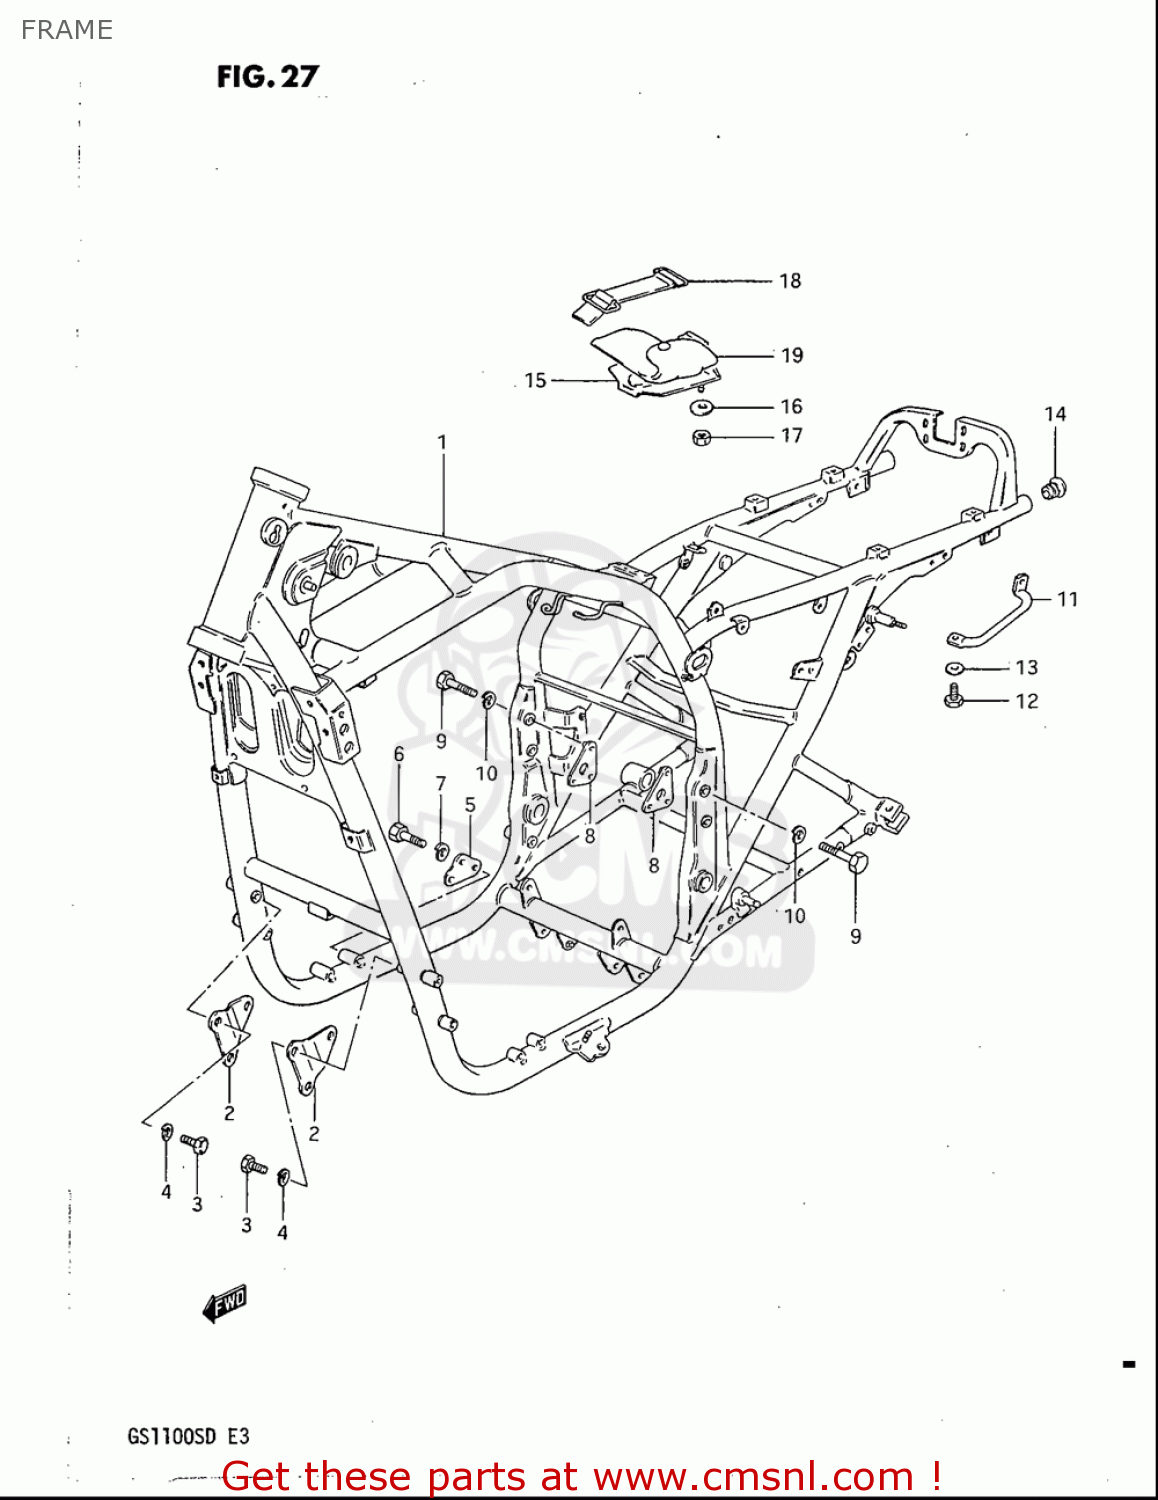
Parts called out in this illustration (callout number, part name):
2	PLATE,ENG MTG NO.1
3	BOLT
4	WASHER,LOCK
5	PLATE,ENG MTG NO.2
6	BOLT(8X18)
7	WASHER,LOCK
8	PLATE,ENG MTG NO.4
9	BOLT(8X32.5)
10	WASHER,LOCK
11	GRIP,STAND
12	BOLT
13	WASHER
14	CAP(OD:26)
15	HOLDER,TOOL
16	WASHER(6.5X30X1.6)
17	NUT
18	BAND
19	TOOL ASSY
